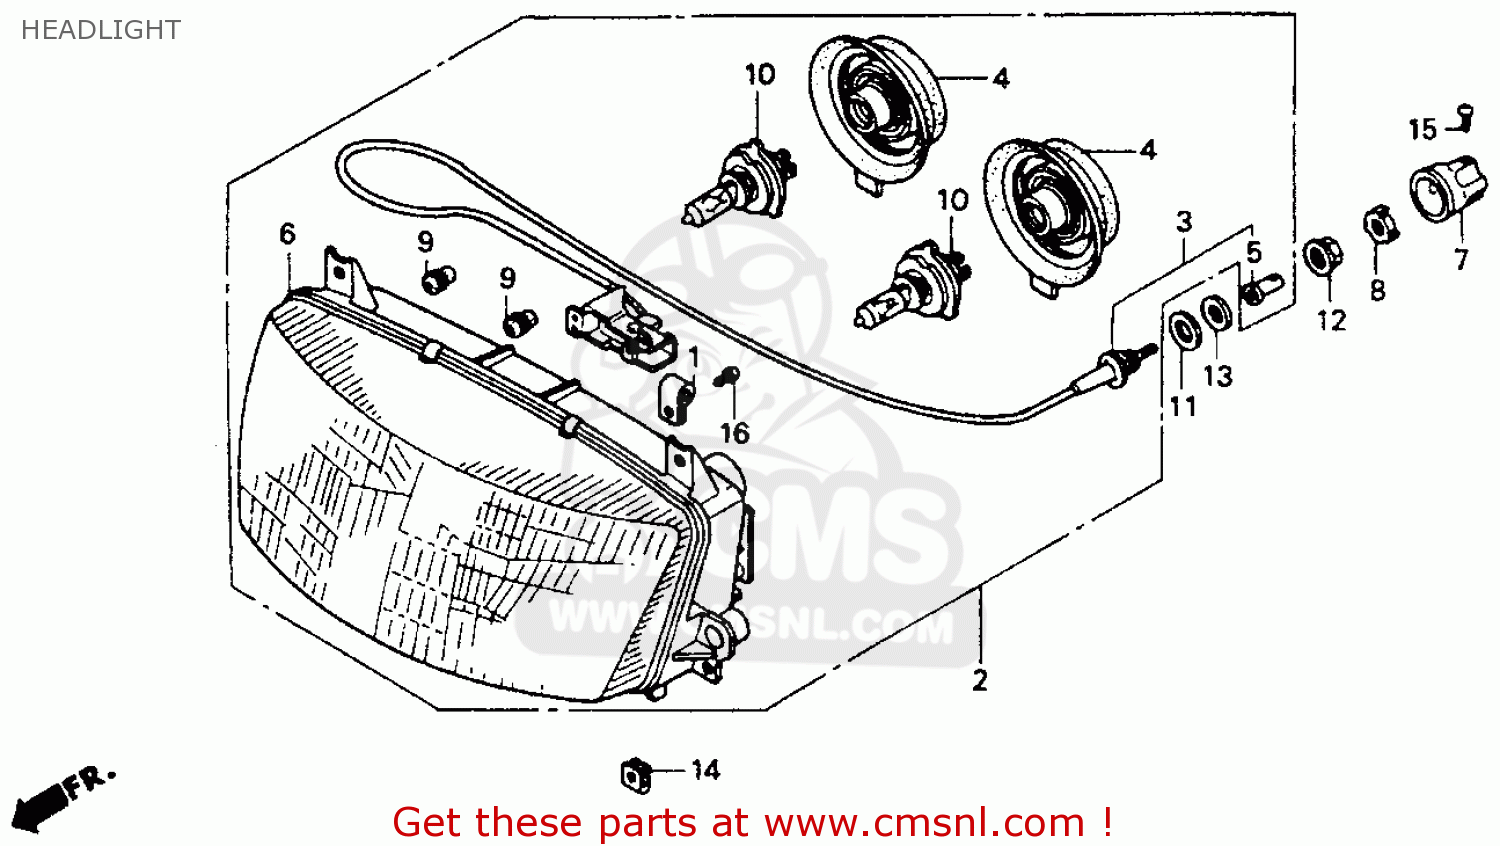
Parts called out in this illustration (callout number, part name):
1	CLAMP
2	HEADLIGHT ASSY.(1
3	CABLE COMP.
4	COVER,RUBBER
5	NUT BEAM ADJUST
6	HEADLIGHT UNIT
7	KN0B BEAM ADJUST
8	WASHER SET
9	BUSH,RUBBER
10	BULB,HEADLIGHT (1
11	WASHER,SPECIAL
12	NUT,SPECIAL 16MM
13	WASHER,SPECIAL
14	NUT,CLIP,5MM
15	SCREW,TAPPING 4MM
16	SCREW,TAP.,4X12
